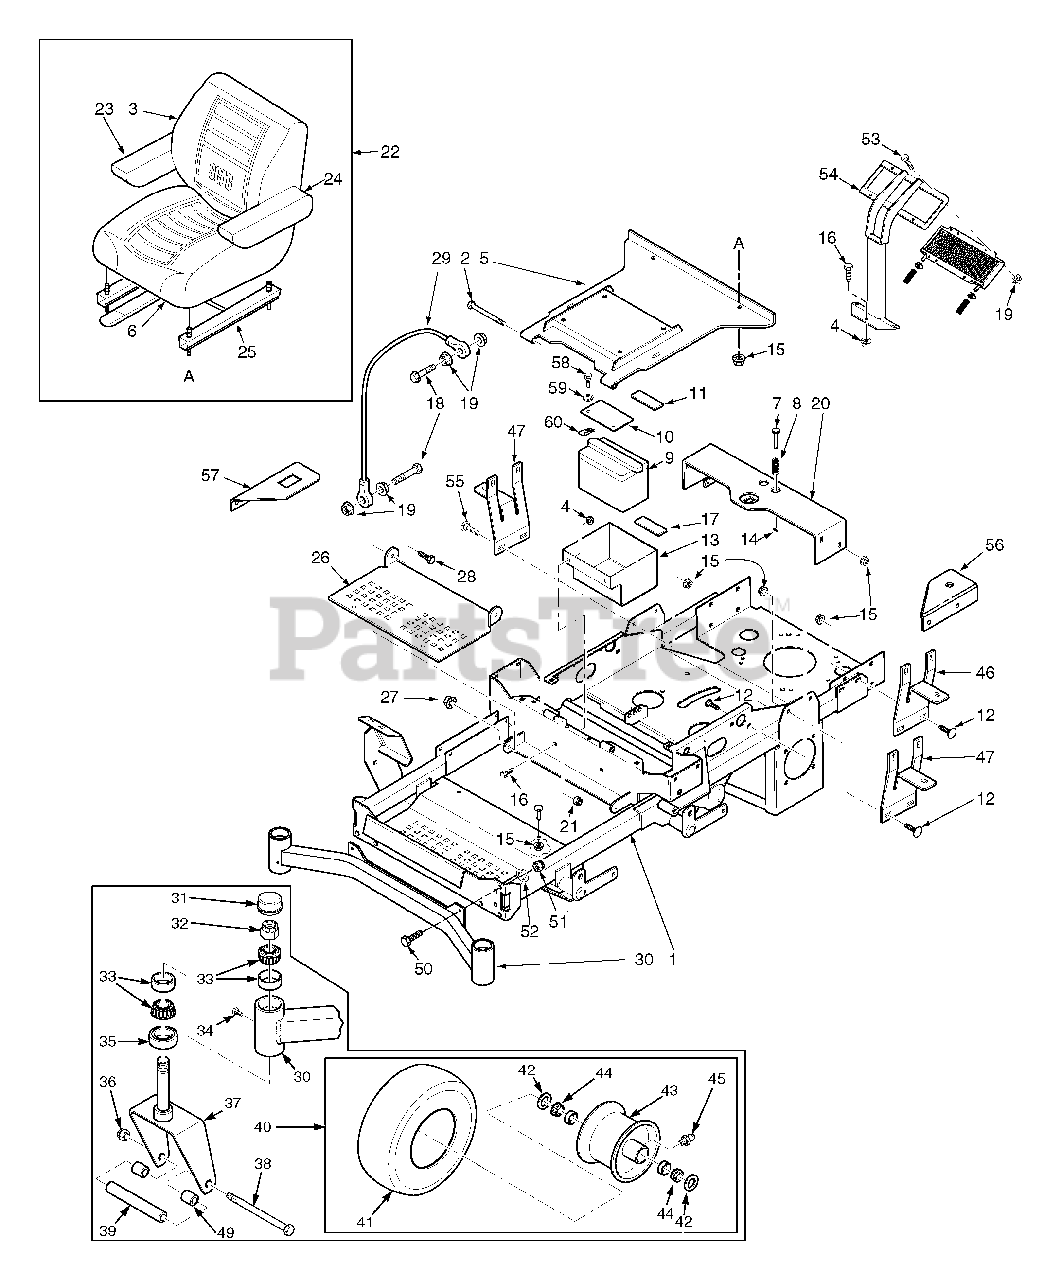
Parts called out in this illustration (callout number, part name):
1	Main Frame Assembly w/decals
2	Bolt, Hex Head 5/16-18 x 3-3/4"
3	Back Cover
4	Nut, Serr. Flange 3/8-16
5	Plate, Seat Mounting
6	Cushion Cover
7	Pin Retainer, Spring
8	Spring
9	Battery
10	Battery Cover
11	Battery Hold Down Pad
12	Bolt, Carr. 5/16-18 x 3/4"
13	Battery Box
14	Roll Pin, Spring 5/32 x 3/4"
15	Nut, Serr. Flange 5/16-18
16	Bolt, Hex Head 3/8-16 x 1"
17	Pad, Rubber
18	Bolt, Hex Head 1/4-20 x 1-1/4"
19	Nut, Serr. Flange 1/4-20
20	Seat Base Support
21	Nut, Elastic Stop 5/16-18
22	Seat Assembly w/ adj. rails
23	Armrest Cover
24	Armrest Cover
25	Seat Track Set
26	Footplate
27	Nut, Elastic Stop 3/8-16
28	Bolt, Hex Head 3/8-16 x 1"
29	Cable, Seat Stop
30	Weldment, Caster Support (61A)
31	Cap, Grease
32	Nut, Elastic Stop 1.0-14
33	Bearing Set
34	Plug, 1/4-28
35	Seal, 2.0" OD x 1.625" ID
36	Nut, Elastic Stop 1/2-13
37	Yoke, Front Caster Wheel
38	Bolt, Hex Head 1/2-13 x 9-1/2"
39	Sleeve
40	Caster Wheel Assembly
41	Tire, 13 x 6.5 Smooth
43	Rim
44	Roller Bearing
45	Fitting, Grease
46	Mounting Bracket, Oil Tank
47	Mounting Bracket, Fuel Tank
48	Seat Pan
49	Spacer, Caster Wheel
50	Bolt, Hex Head 7/16-14 x 1-1/4"
51	Nut, Elastic Stop 7/16-14
52	Lockwasher, 7/16
53	Bolt, Hex Head 1/4-20 x 5/8"
54	Support Weldment, Oil Cooler
55	Bolt, Carriage 5/16-18 x 1"
56	Bracket, Fuel Valve
57	Bracket, Hour Meter
58	Bolt, Hex Head 3/8-16 x 1-1/4"
59	Lock Washer. 3/8 Spring
60	U-Nut, 3/8-16
